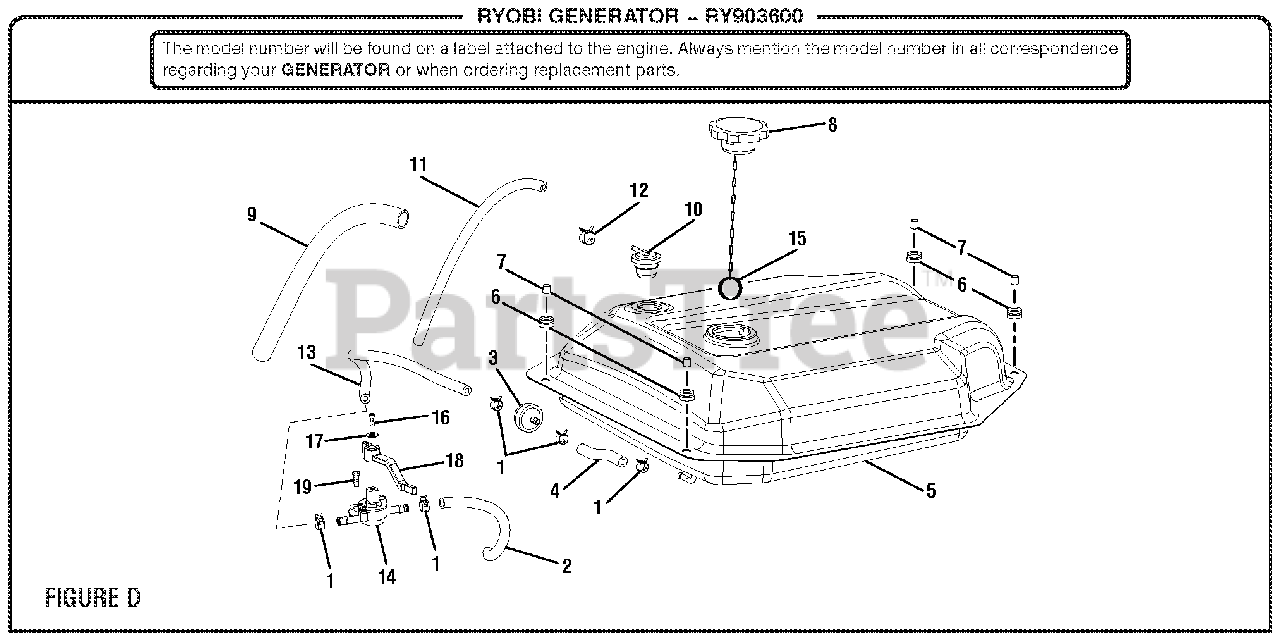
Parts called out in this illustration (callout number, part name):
1	Fuel Line Clamp (1/2 in.)
2	Fuel Hose (175 mm)
3	Fuel Filter Inline (1/4 in.)
4	Fuel Hose (80 mm)
5	Fuel Tank
9	Fuel Hose Cover (200 mm)
10	Vapor Vent
11	Vapor Hose
12	Fuel Line Clamp (7/16 in.)
13	Fuel Hose (300 mm)
14	Fuel Valve
15	Ring Clip
16	Bolt (M4 x 10 mm, Pan Hd.)
17	Washer (ID4.3 x OD10 x 0.9t)
18	Control Lever
19	Screw (M6 x 10 mm, Pan Hd.)
